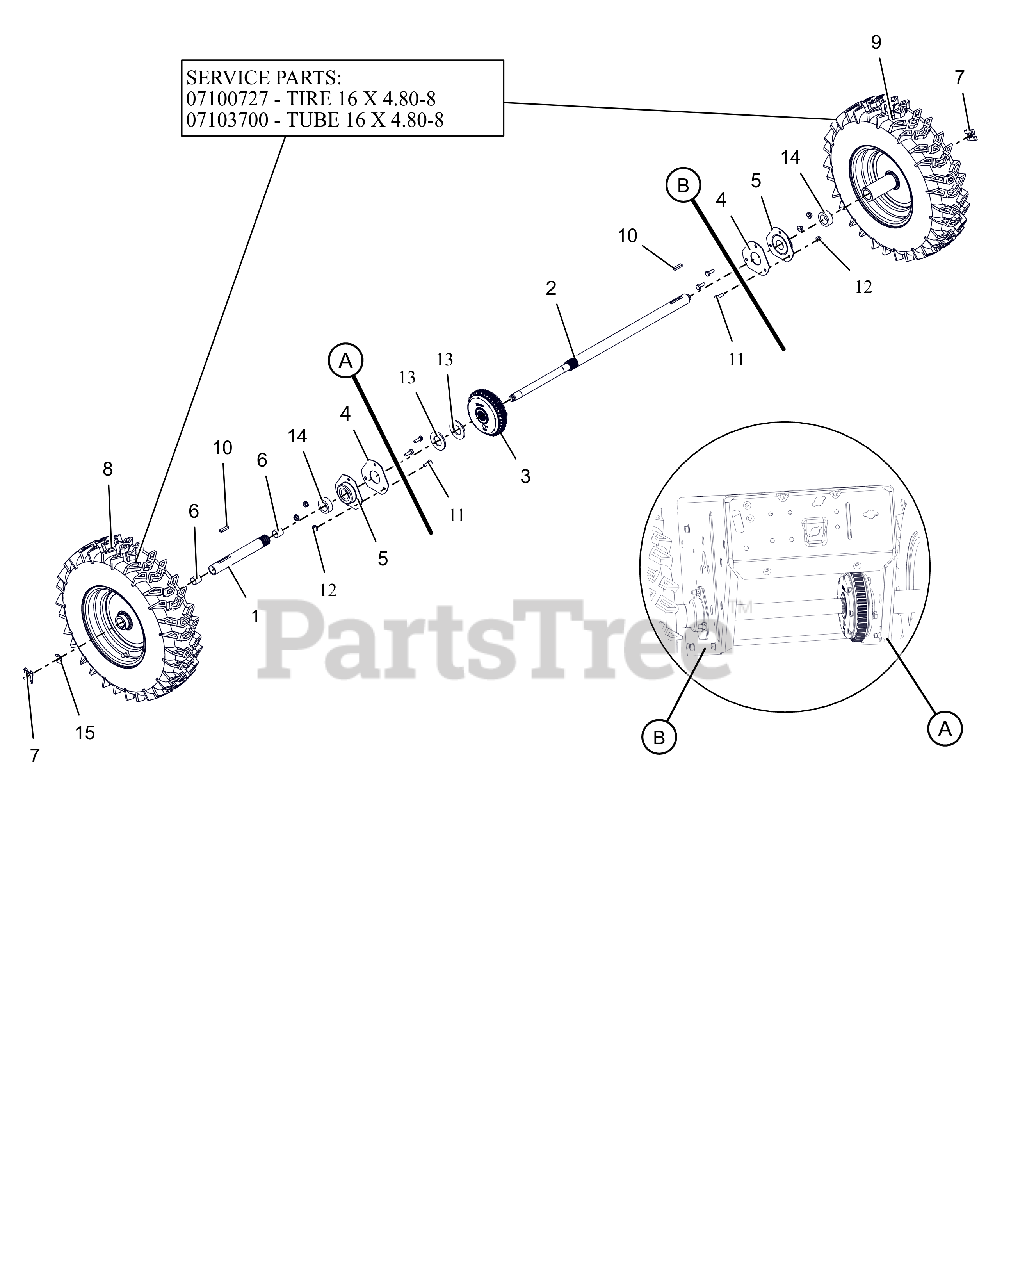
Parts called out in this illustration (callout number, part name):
1	AXLE, SHORT-AUTO W/BUSHINGS
2	AXLE, LONG-PRO AUTO DIFF
3	DIFFERENTIAL, AUTOMATIC
4	PLATE, BEARING SPACER
5	BRG-FLG 1.003/1.000 3 BOLT
6	BSHG-SLV .706X.764X.75 BRZ
7	CLIP, SNAP .625 DIA
8	TIRE/WHEEL,RH 16X4.8-8 DIFF T2
8-9	TIRE, 4.80-8 K478
8-9	TUBE
9	TIRE/WHEEL,LH 16X4.8-8 DIFF T2
10	KEY-RECT .25X.188X1.00
11	BLT, HEX .25-20X.75 G5 ZCC
12	NUT-LK-CTR-FLG .25-20 ZC120
13	WSHR, FLT 1.062X2.000X.134 ZCC
14	SPACER, PRO AXLE BEARING
15	RG-RTNG-EXT .625X.042
